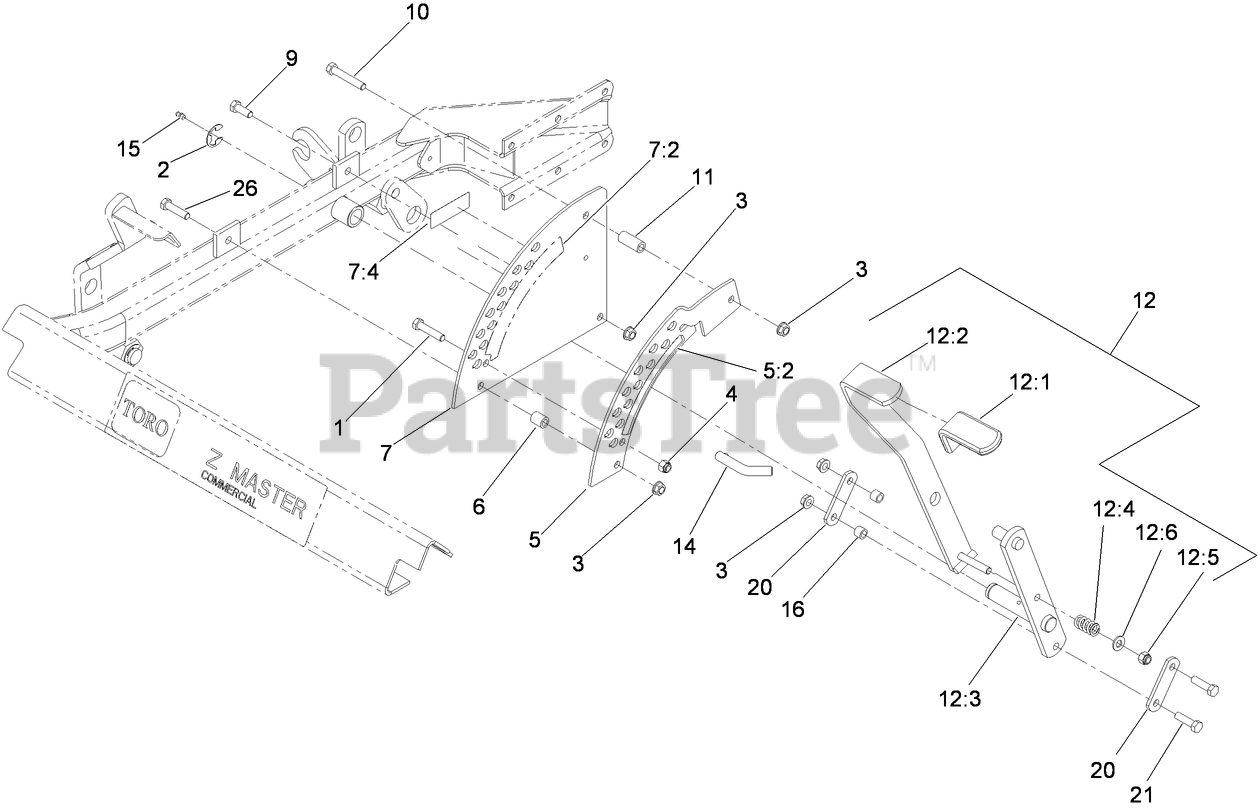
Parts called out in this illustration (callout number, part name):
1	SCREW-HH
2	RING-RETAINING, EXT
3	NUT-HHF, WHIZ
4	NUT-LOCK, NI
5	PLATE-HOC, INNER
5:2	DECAL-DECK HEIGHT, INNER
6	BUSHING-LEVER, LIFT
7	PLATE-HOC, OUTER
7:2	DECAL-DECK HEIGHT, OUTER
7:4	DECAL-ARRESTER, SPARK
9	SCREW-HH
10	SCREW-HH
11	BUSHING-LEVER, LIFT
12	DECK LIFT HANDLE ASM
12:1	GRIP-LEVER, LIFT
12:2	HANDLE-LIFT
12:3	LIFT ARM ASM
12:4	SPRING-COMPRESSION
12:5	NUT-LOCK, NI
12:6	WASHER-FLAT
14	PIN-HOC
15	FITTING-GREASE
16	Bushing
20	ARM-LIFT, DECK
21	SCREW-HH
26	SCREW-HH
